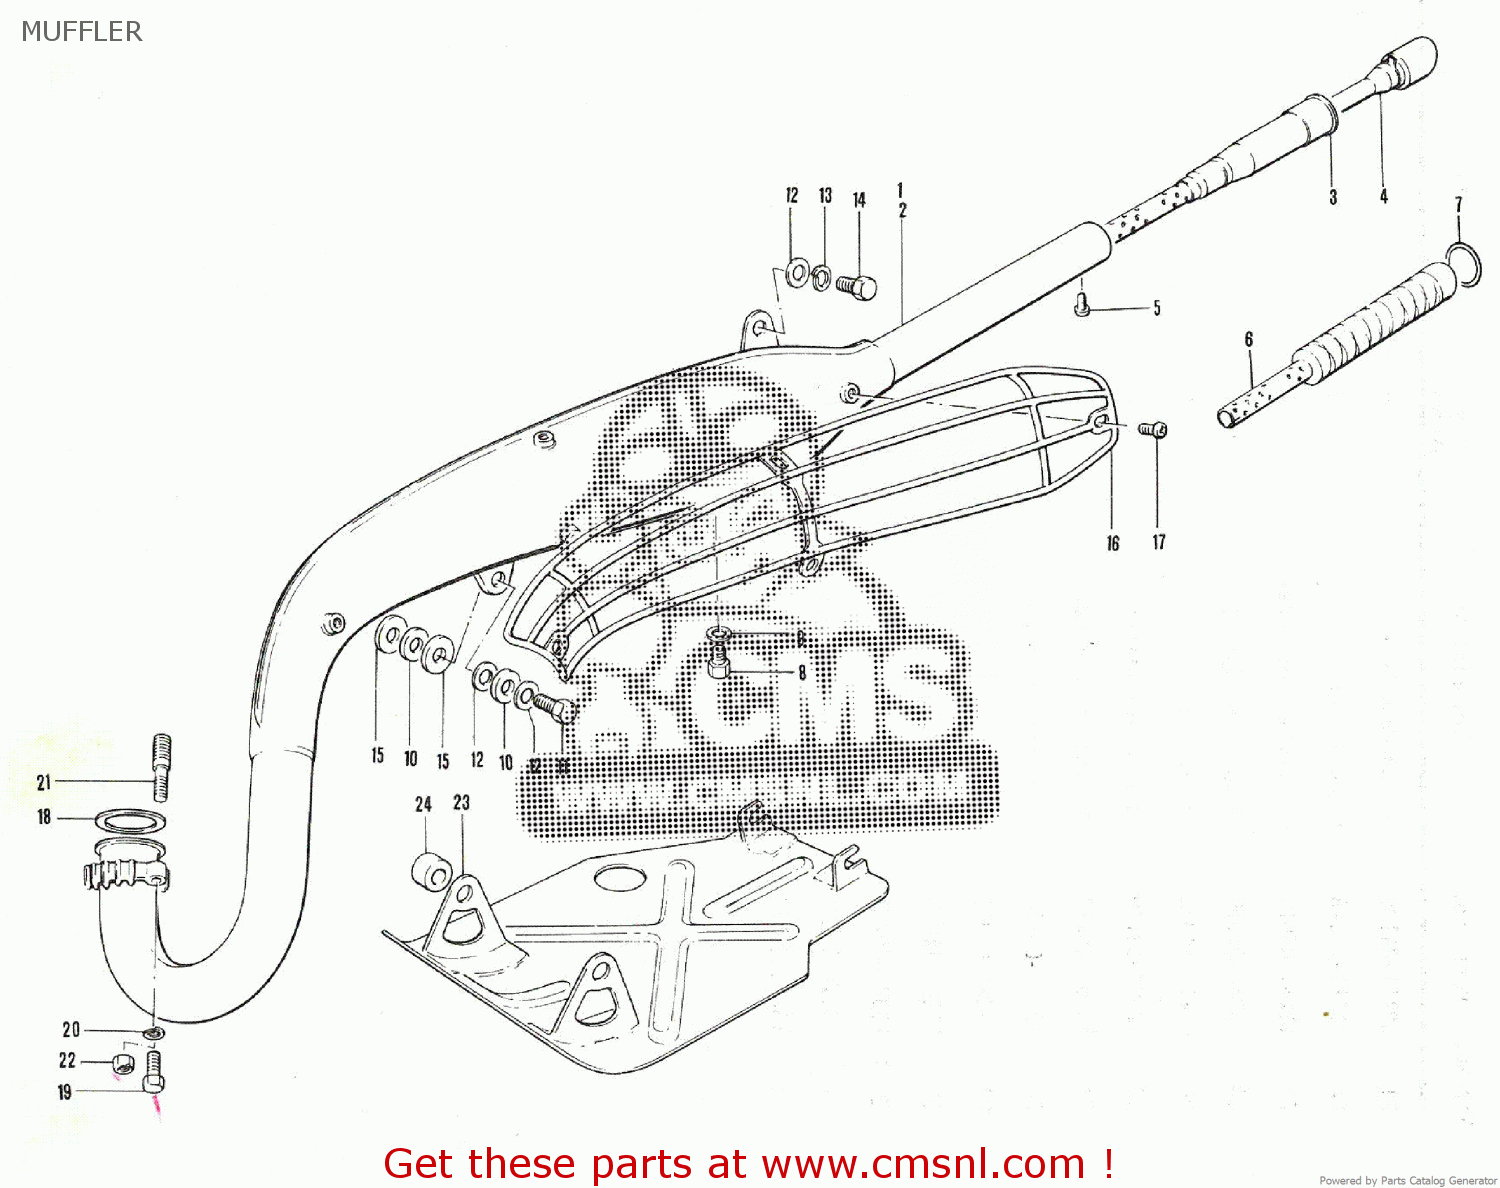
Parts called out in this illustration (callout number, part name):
2	MUFFLER ASSEMBLY
3	ARRESTER,SPARK
4	TUBE,MUFFLER CLEAN OUT
5	SCREW(5X6)
8	BOLT 10X9
9	GASKET(10X14X3.6) (NAS)
10	CUSHION
11	SMALL HEXAGON BOLT
12	WASHER
13	LOCK WASHER
14	BOLT
15	WASHER
16	COVER,MUFFLER
17	SCREW
18	GASKET,EXHAUST PIPE (NAS)
19	BOLT
20	LOCK WASHER
21	STUD
22	NUT
23	GROMMET
24	SPACER
